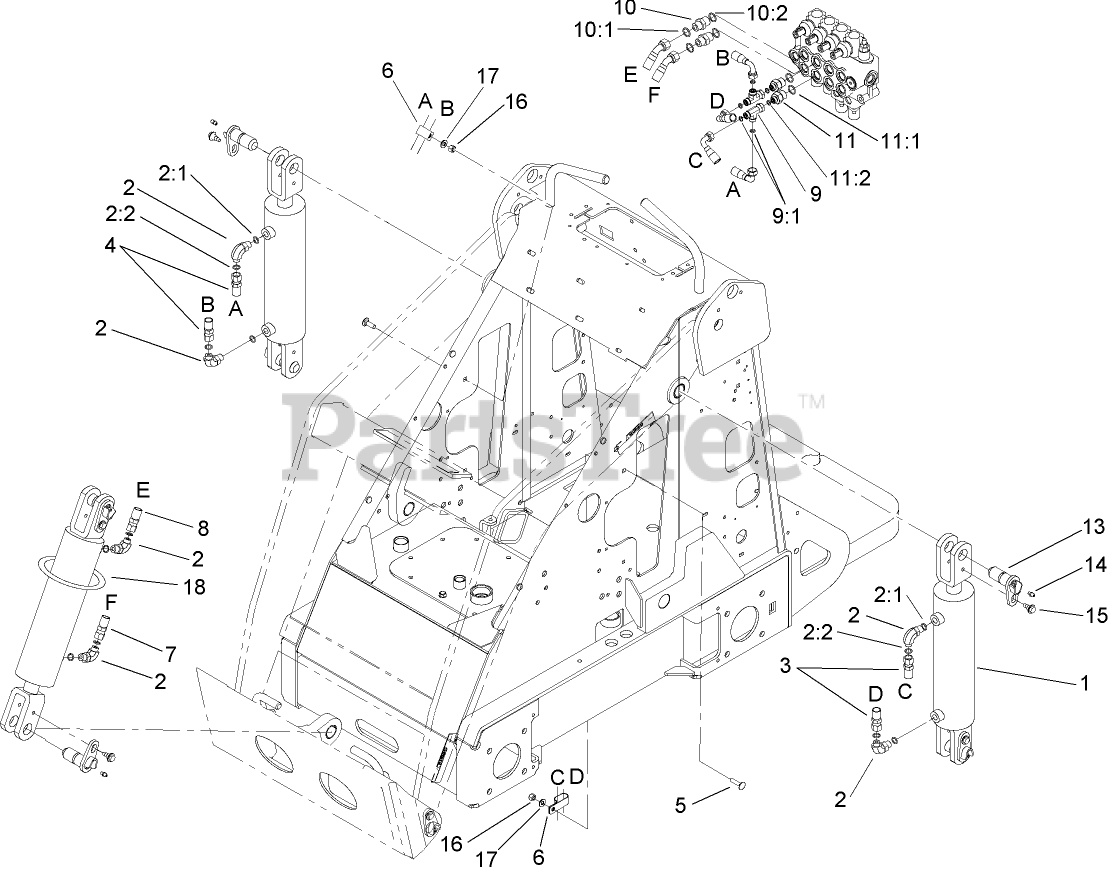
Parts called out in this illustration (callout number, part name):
1	HYD CYLINDER ASM
2	FITTING-ELBOW 90
2:1	O-RING
2:2	O-RING
3	HYD HOSE ASM
4	HOSE-HYD
5	SCREW-CARR
6	CLAMP-R, DOUBLE
7	HOSE-HYD
8	HOSE-HYD
9	FITTING-HYD
9:1	O-Ring
10	FITTING-STRAIGHT
10:1	O-RING
10:2	O-RING
11	FITTING-STR
11:1	O-RING
11:2	O-RING
13	PIN-PIVOT
14	FITTING-GREASE
15	BOLT-SHOULDER
16	NUT-LOCK, NI
17	WASHER-PLAIN
18	TIE-CABLE
